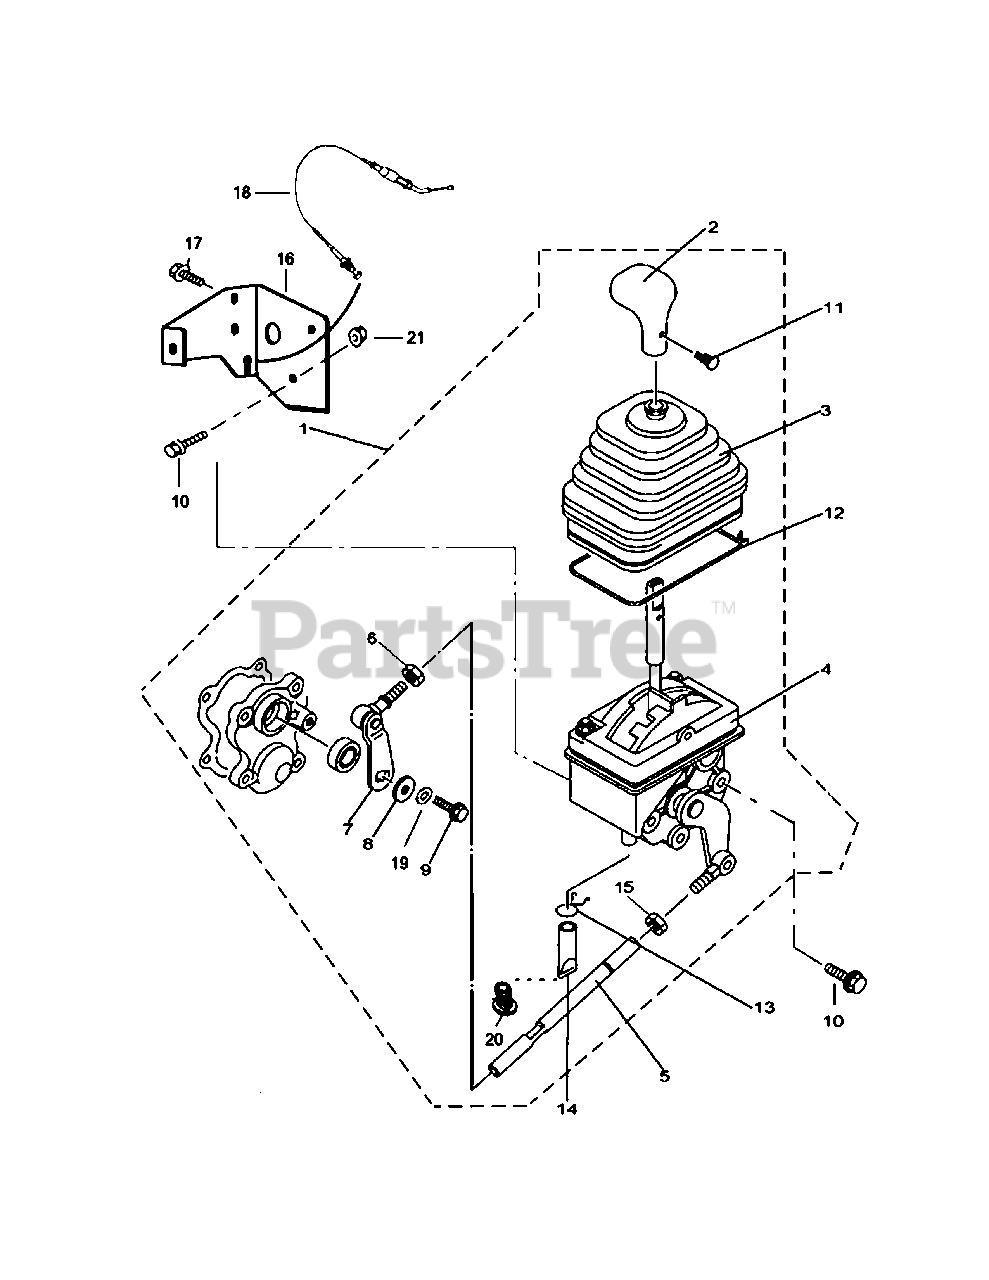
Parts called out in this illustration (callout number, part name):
1	Gear Shifter Assembly
2	Gearshift Knob
3	Gearshift Boot
4	Gearshift Assy
5	Gear Shift Rod
7	Gearshift Tie Assy
8	Washer6×18×1.6
9	Hexagon Flange Bolt M6×16
10	Hexagon Flange Bolt M8×16
11	Plastic Screw
12	Rubber Cover Clamp
14	Water Leakage Pipe Cap
15	Adjust Nut M8(L)
16	Gear Shifting Support
17	Hexagon Flange Bolt M6×12
18	Reverse Cable
19	Spring Washer -6
21	Nut M8
